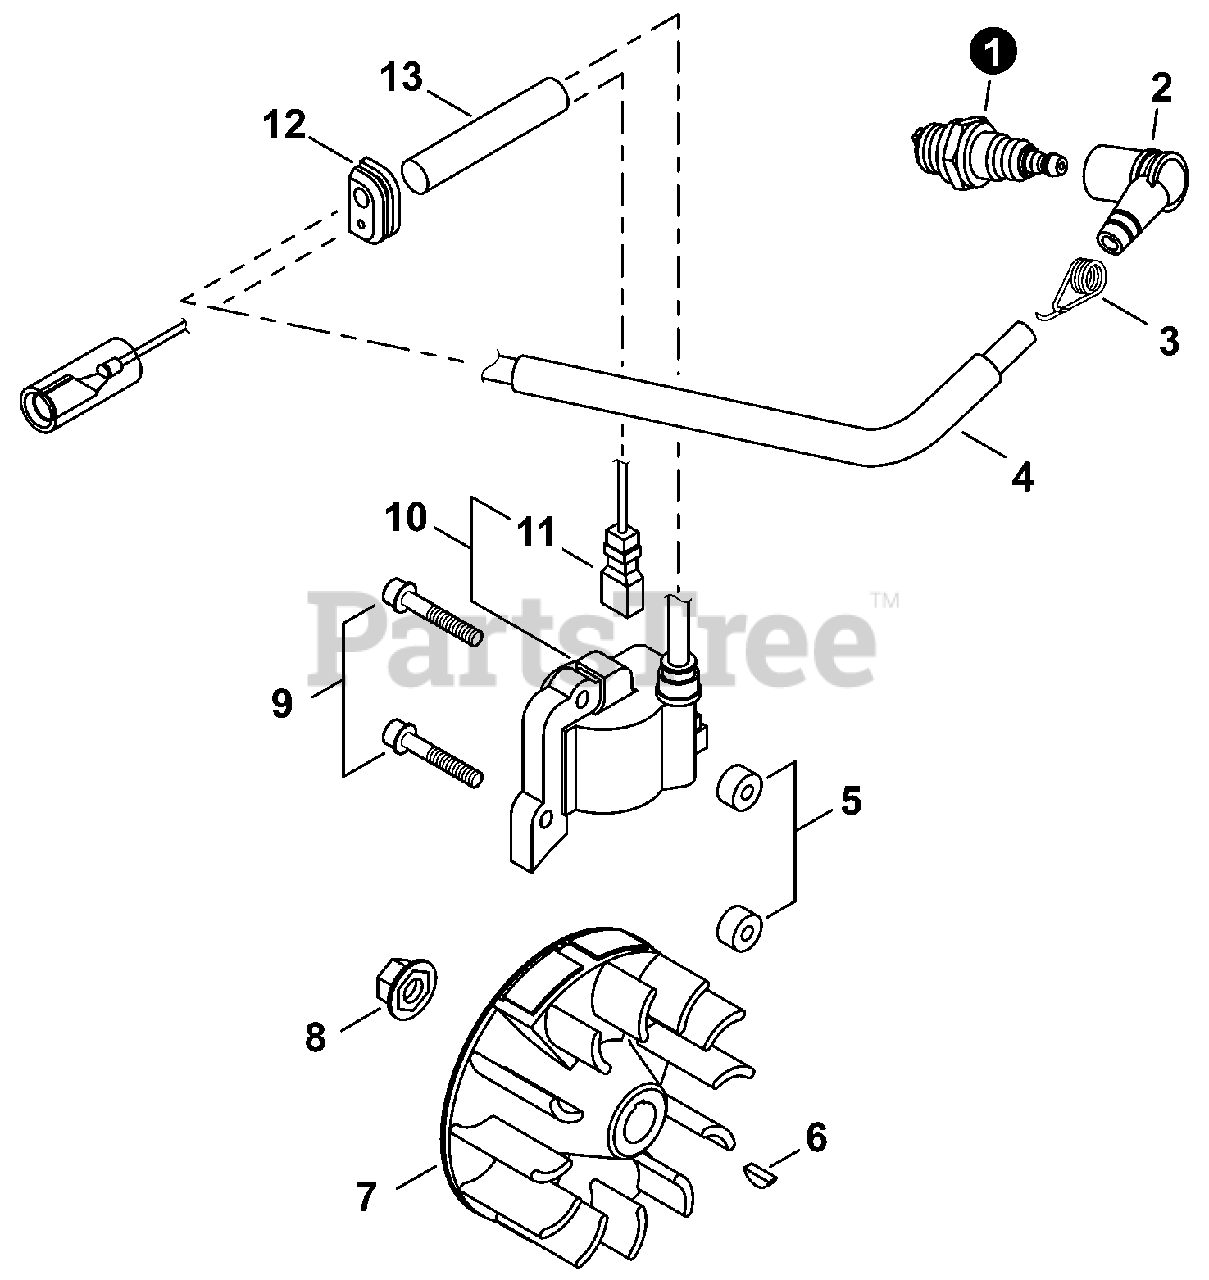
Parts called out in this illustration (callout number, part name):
1	SPARK PLUG - BMR6A
2	CAP, SPARK PLUG
3	TERMINAL, SPARK PLUG
4	TUBE, INSULATOR
5	INSULATOR 4.2x11x6
6	KEY, WOODRUFF 3x10
7	FLYWHEEL
9	BOLT 4x26
10	COIL ASSY, IGNITION
12	GROMMET
13	TUBE, IGNITION COIL
